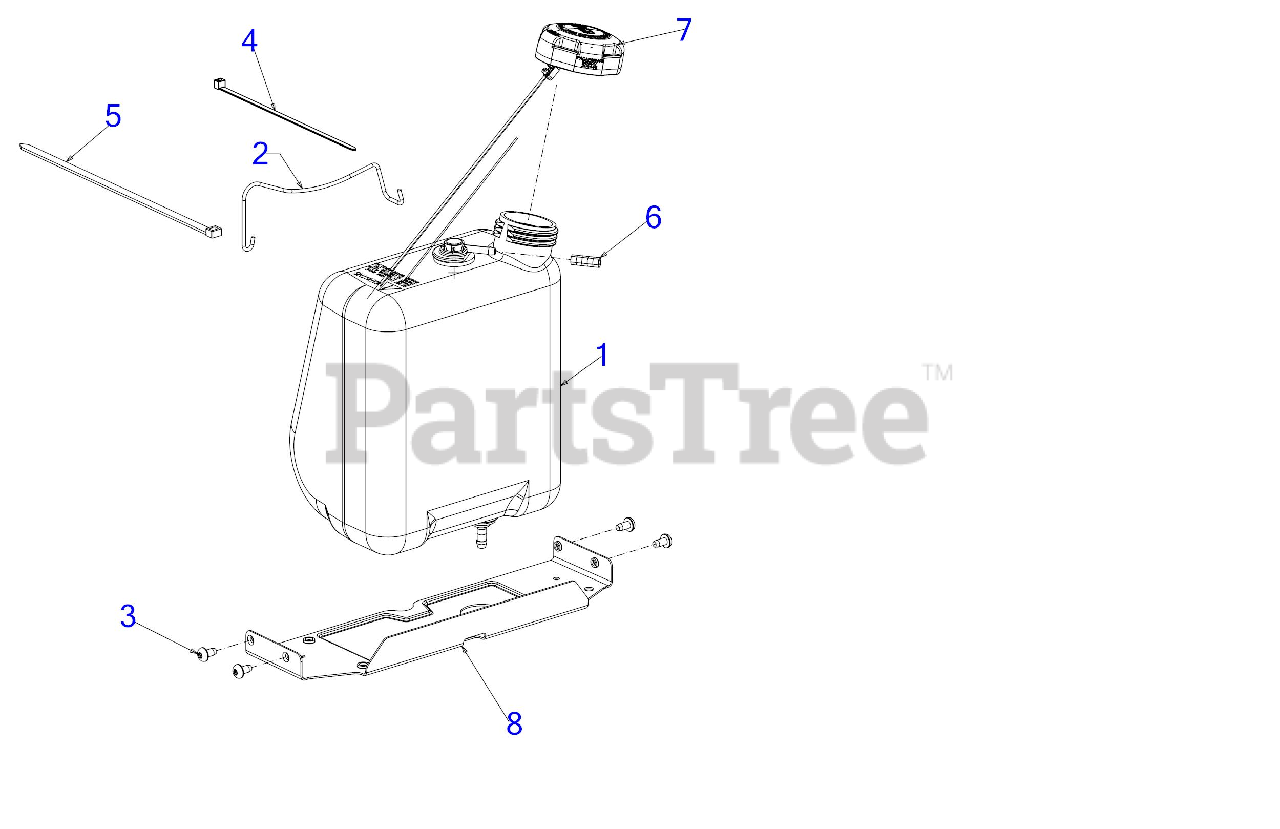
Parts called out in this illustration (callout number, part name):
1	FUEL TANK ASSEMBLY
2	BATTERY ROD ASSEMBLY
3	SCREW 1/4-20 x .5
4	7" CABLE TIE
5	CABLE TIE 36"
6	VENT HOSE 3/16 ID
7	FUEL CAP W/TETHER
